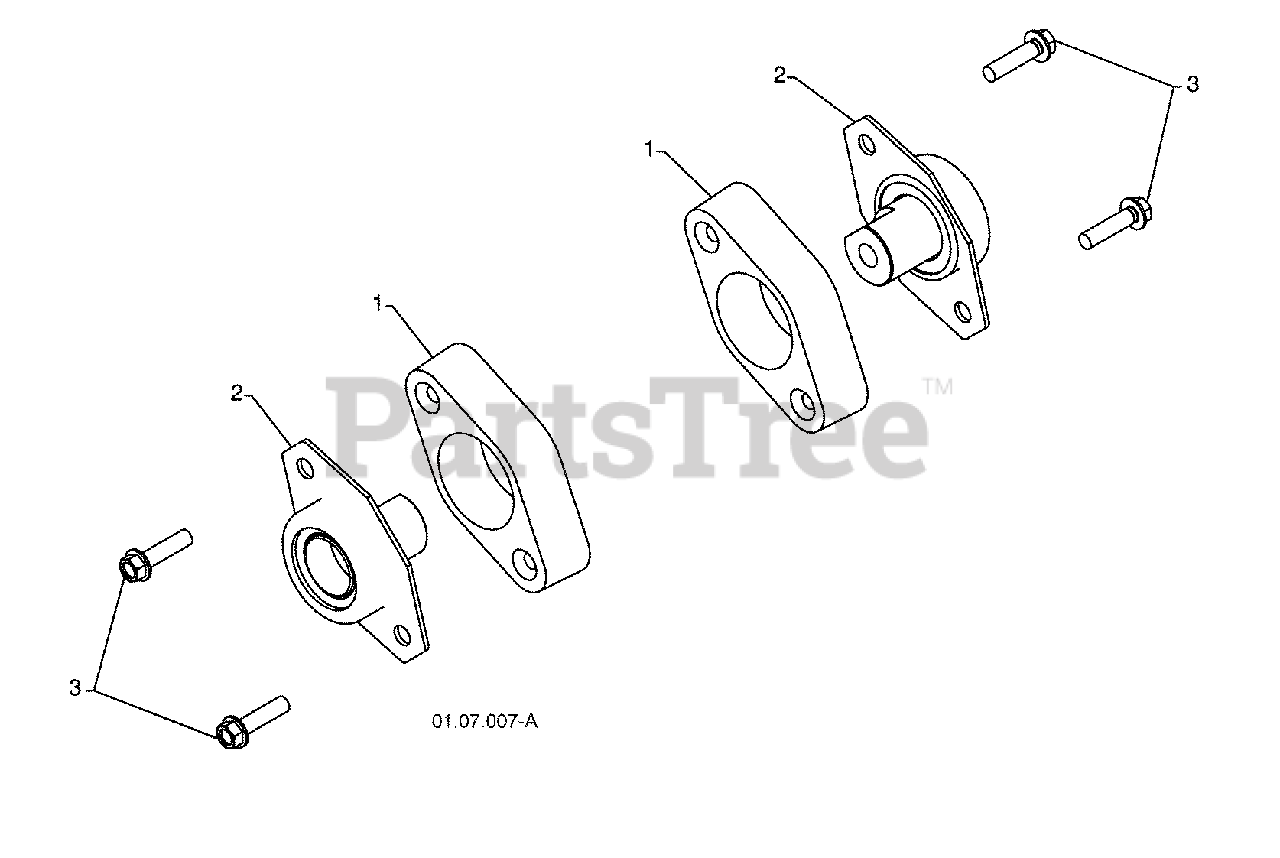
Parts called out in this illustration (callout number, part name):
1	PLASTIC RETAINER
2	AUGER BALL BEARING
3	SCREW 5/16-18 X 1.00
